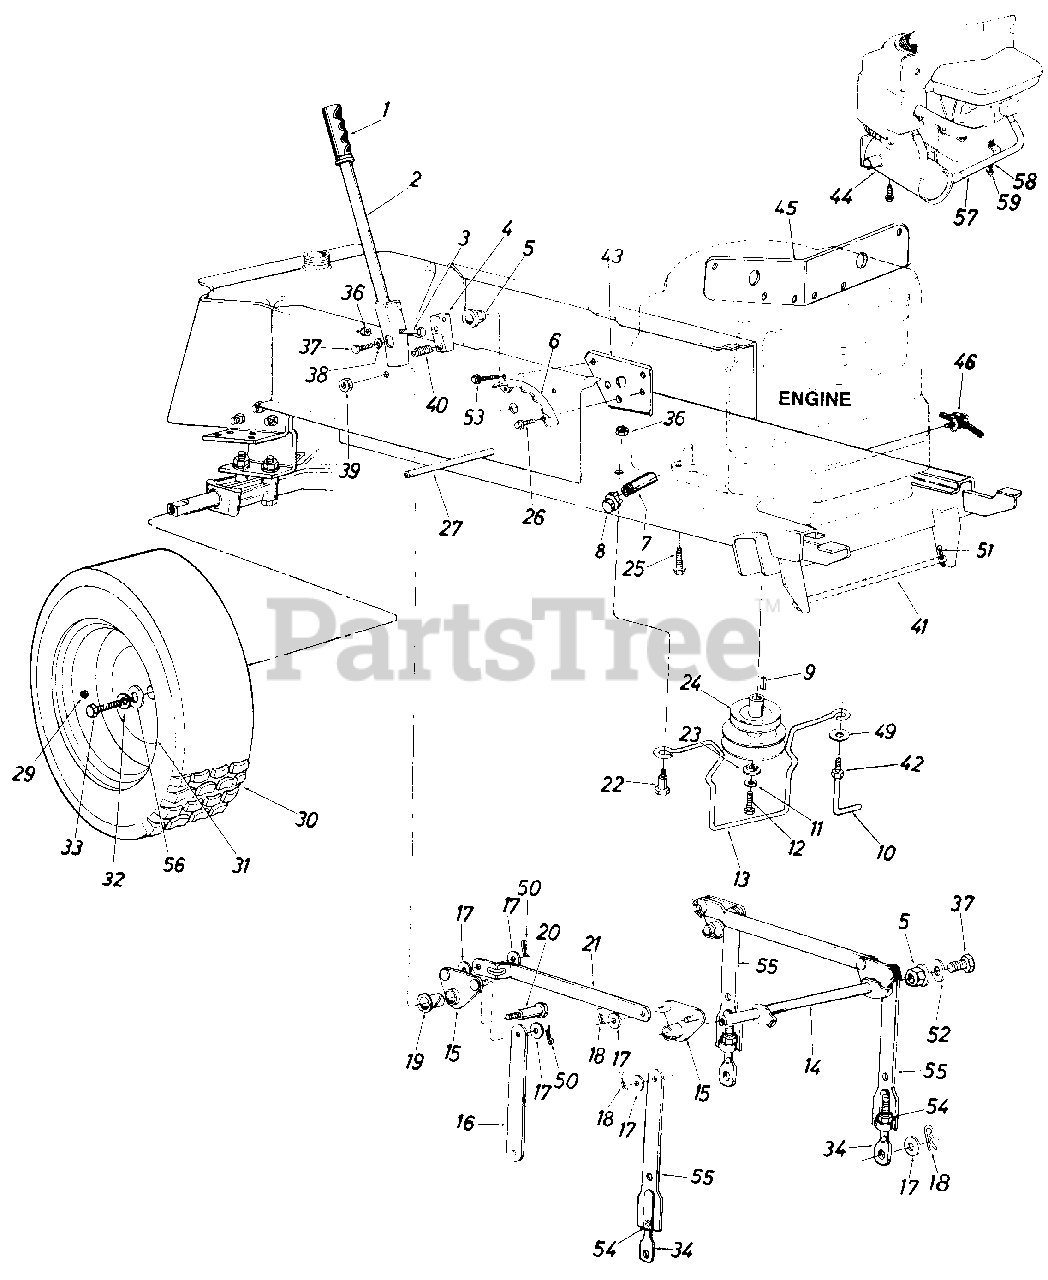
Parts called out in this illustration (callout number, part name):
1	Grip
2	Lift Handle Ass'y.
3	Hex Scr. 5/16-18 x 1.50" Lg.
4	Lift Shaft Drive
5	Plastic Hex Brg. 518" I.D.
8	Pipe Cap 3/8-18 Npt.
9	Sq. Key 114" x 1.50" Lg.
10	Belt Guard Lock Pin
11	L-Wash. 7/16" Scr.
12	Hex Scr 7/16-20 x 1.50" Lg.
13	Belt Guard
14	Lift Shaft Ass'y.
15	Lift Pivot Brkt. Ass'y.
17	Fl-Wash. 112" I.D. x 1.00" O.D. x .090
18	Hairpin Cotter
19	Nyliner 518" I.D. x .88" Lg.
20	Shld. Scr. 518" Dia. x .96" Lg. 3/8-16
23	Flat Wash. .44" I.D. x 1.25" O.D. x .17
24	Two-Step Engine Pulley
25	Hex Wash. Hd. Scr. 3/8-16 x 1.25" Lg.
26	Hex Thd. Rolling Scr. 5/16-24 x .50" Lg.
27	Running Board Rod
29	Air Valve
30	Rear Wheel Ass'y. Comp.
31	Rear Wheel Rim Only
32	Bell-Wash. .345" I.D. x .88" O.D.
33	Hex Bolt 5/16-24 x .75" Lg.
34	Eye Bolt Adj. Link 1/2-13 Thd.
36	Hex Cent. L-Nut 5/16-18 Thd.
37	Hex Scr. 5/16-24 x .62" Lg.
38	L-Wash. 5/16" I.D.
39	Hex Center L-Jam Nut 3/8-16 Thd.
40	Compression Spring
41	Deck Connecting Rod
42	Hex Nut 5/16-24 Thd.
45	Heat Shield
46	Mounting Clamp
49	Bell-Wash. .39" I.D.
50	Cotter Pin .09 Dia. x 1.0" Lg.
51	Int. Cotter Pin
52	Flat Wash. .34" I.D. x 1.12" O.D. x .125
53	Hex Wash. Hd. AB-Tap Scr. 5/16 x .62" Lg.
54	Hex Nut 1/2-13 Thd.
56	Fl-Wash. .34" I.D. x 2.0" O.D.
57	Inlet Tube
58	Spec. L-Wash. 5/16" I.D.
59	Hex Nut 5/16-18 Thd.
